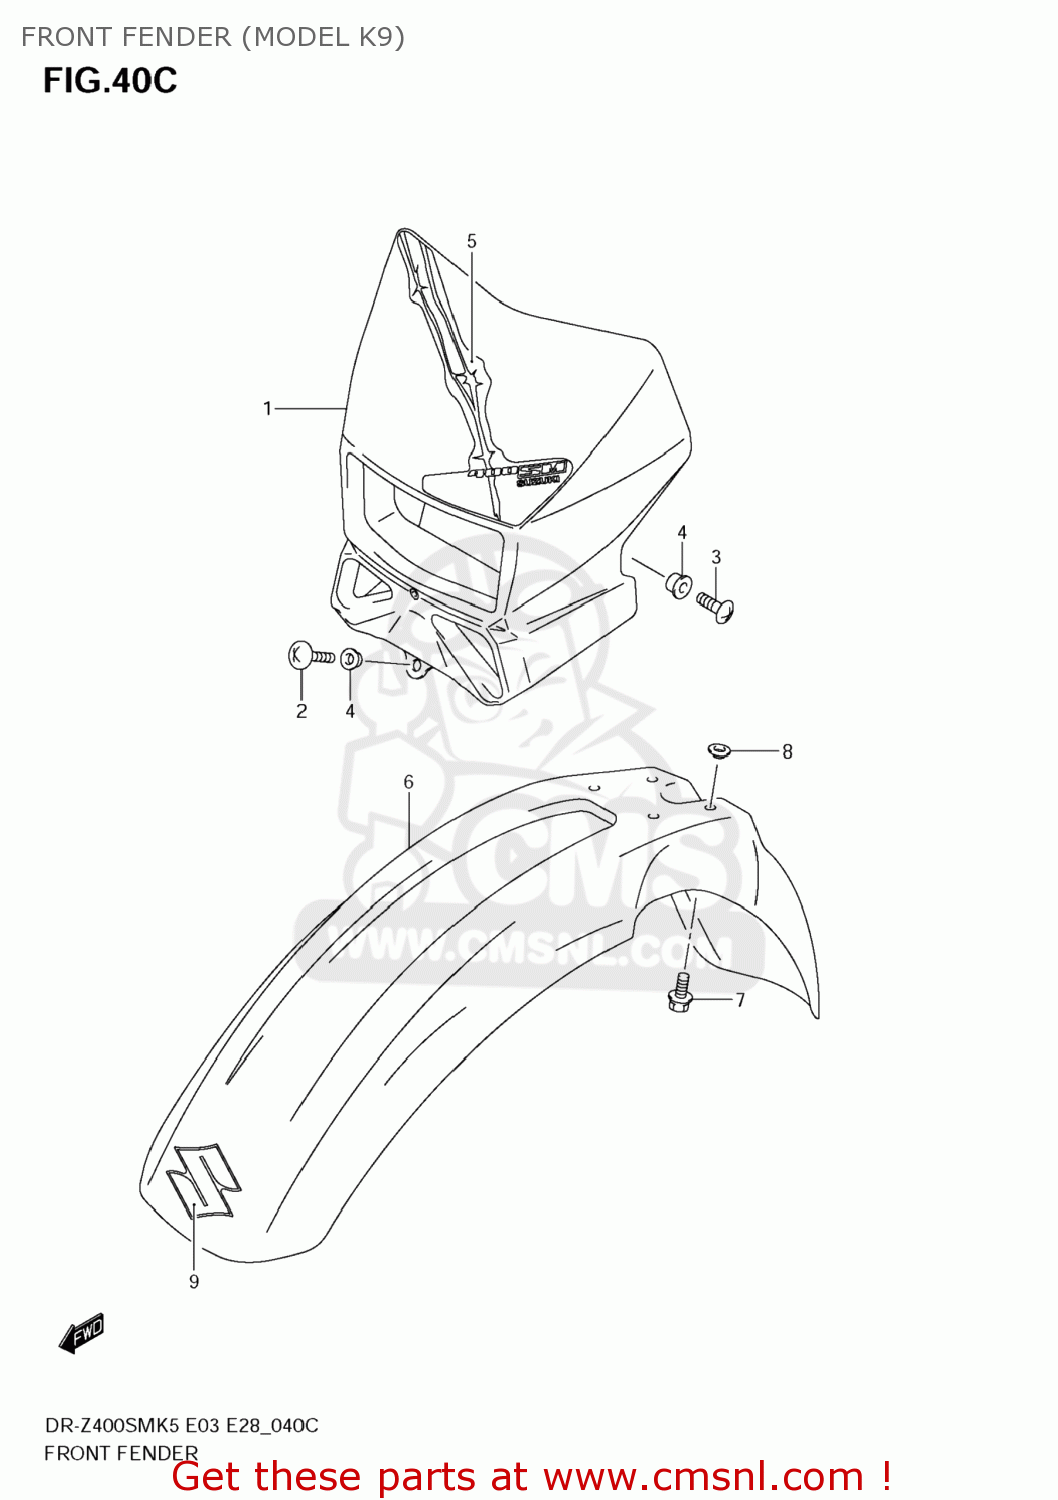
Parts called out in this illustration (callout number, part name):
1	COVER,HEADLAMP
2	SCREW
3	SCREW
4	WASHER
5	TAPE,HEADLAMP HOUSING
6	FENDER,FR
7	BOLT(6X16)
8	WASHER
9	EMBLEM,S
